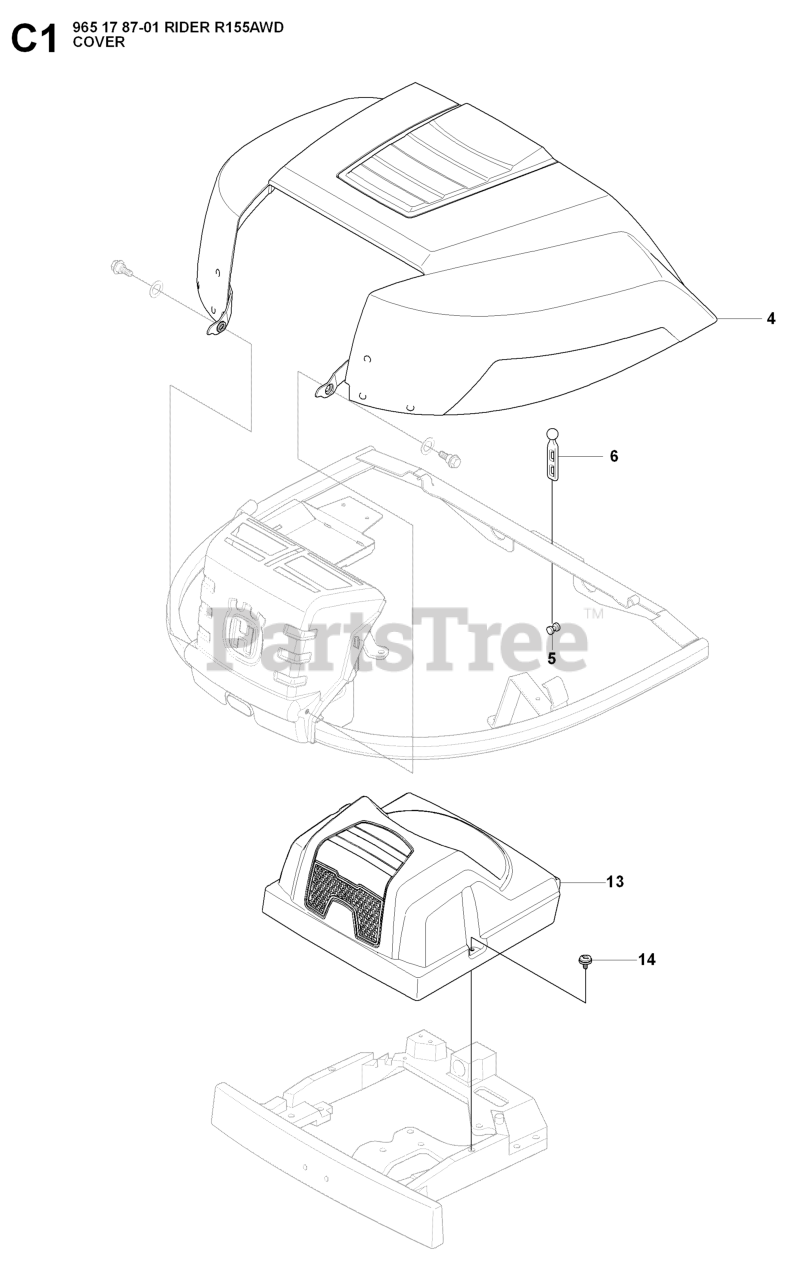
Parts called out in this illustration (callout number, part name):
4	ENGINE HOOD ASSY
6	Support Strap
13	COVER
